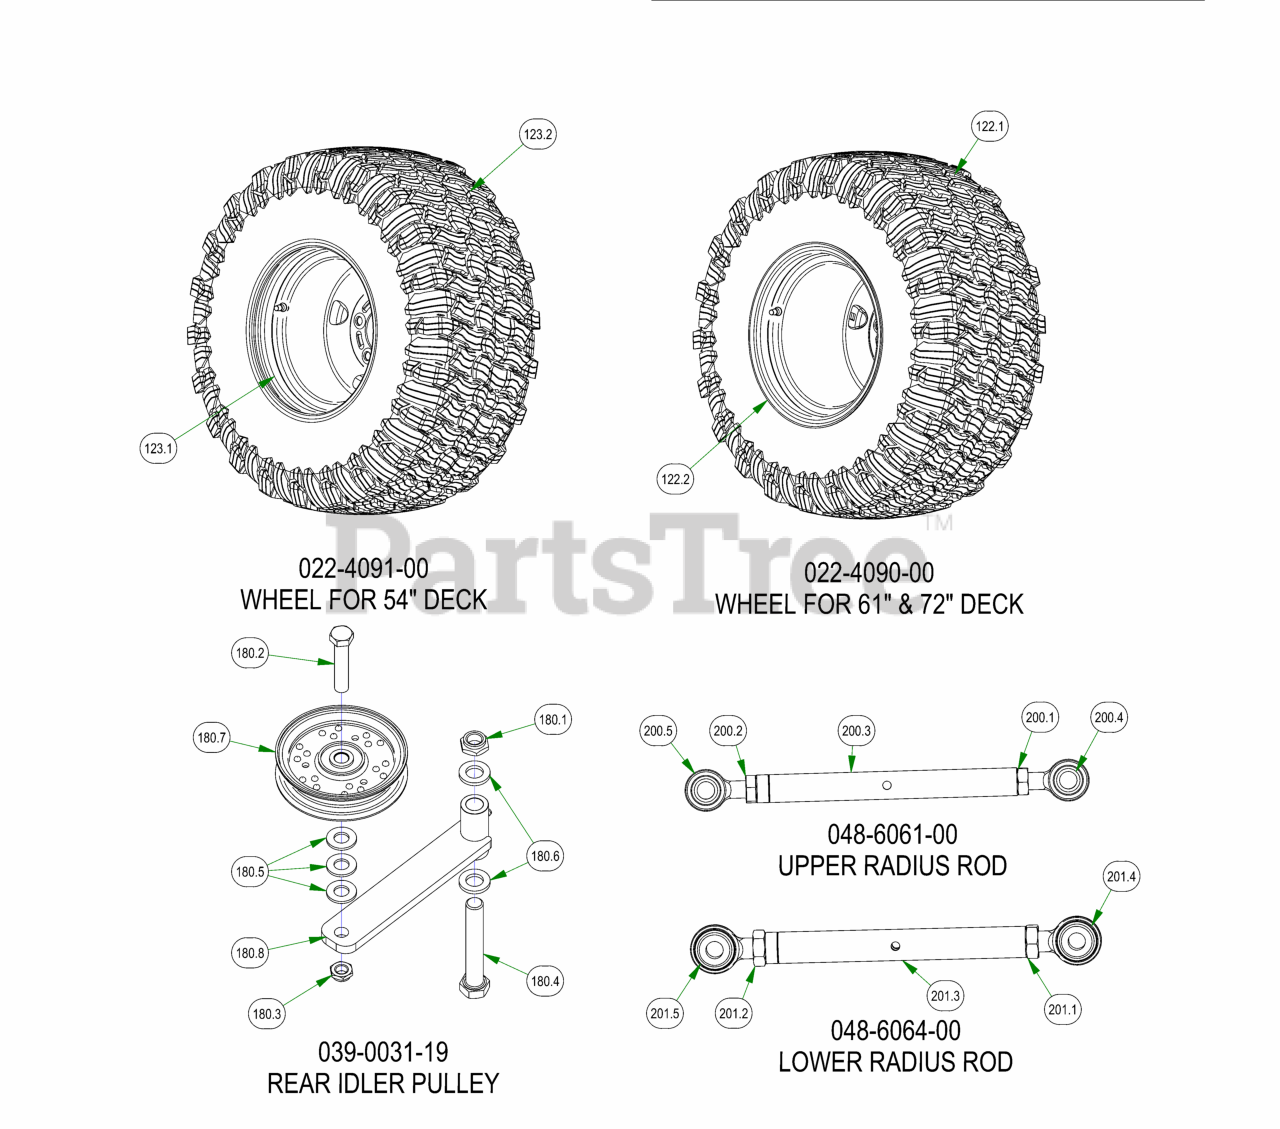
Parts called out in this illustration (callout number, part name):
122	2019 Assy-26x12-12 Reaper Turf -10.5" Rim
122.1	2019 26x12-12 Reaper Turf Tire
122.2	2019 10.5" Wheel
123	2019 Assy-26x12-12 Reaper Turf-8.5" Rim
123.1	12x8.5 Black Wheel
123.2	2019 26x12-12 Reaper Turf Tire
180	2019 Rogue Pump Idler Assy
180.1	5/8-11 NYLON INSERT JAM LOCKNUT ZINC
180.2	1/2-13 X 2-1/2 HEX CAP SCREW GR 5 ZINC
180.3	1/2-13 NYLON INSERT JAM LOCKNUT ZINC
180.4	5/8-11 X 4 HEX CAP SCREW (GR.8) ZINC YELLOW
180.5	1/2 SAE FLAT WASHER (1-1/16" OD) GR.8 ZINC YELLOW
180.6	.635 ID X 1.120 OD X .140 THICK FLAT WASHER NYLON
180.7	4 3/4 Idler Pulley - ABFI-76
180.8	2019 Vertical Suspension Drive Tensioner
200	2019 Suspension Radius Rod Assembly
200.1	5/8-11 HEX JAM NUT ZINC
200.2	NUT, 5/8-18LH
200.3	2019 Suspension Link Body
200.4	2019 RH 5/8" Heim
200.5	2019 LH 5/8" Heim
201	2019 Suspension Radius Rod Assembly
201.1	3/4-16 HEX JAM NUT ZINC
201.2	3/4-16 LH HEX JAM NUT ZINC
201.3	Rear Radius Rod, 3/4 Body
201.4	3/4-16 x 5/8 RH Heim
201.5	3/4-16 x 5/8 LH Heim
